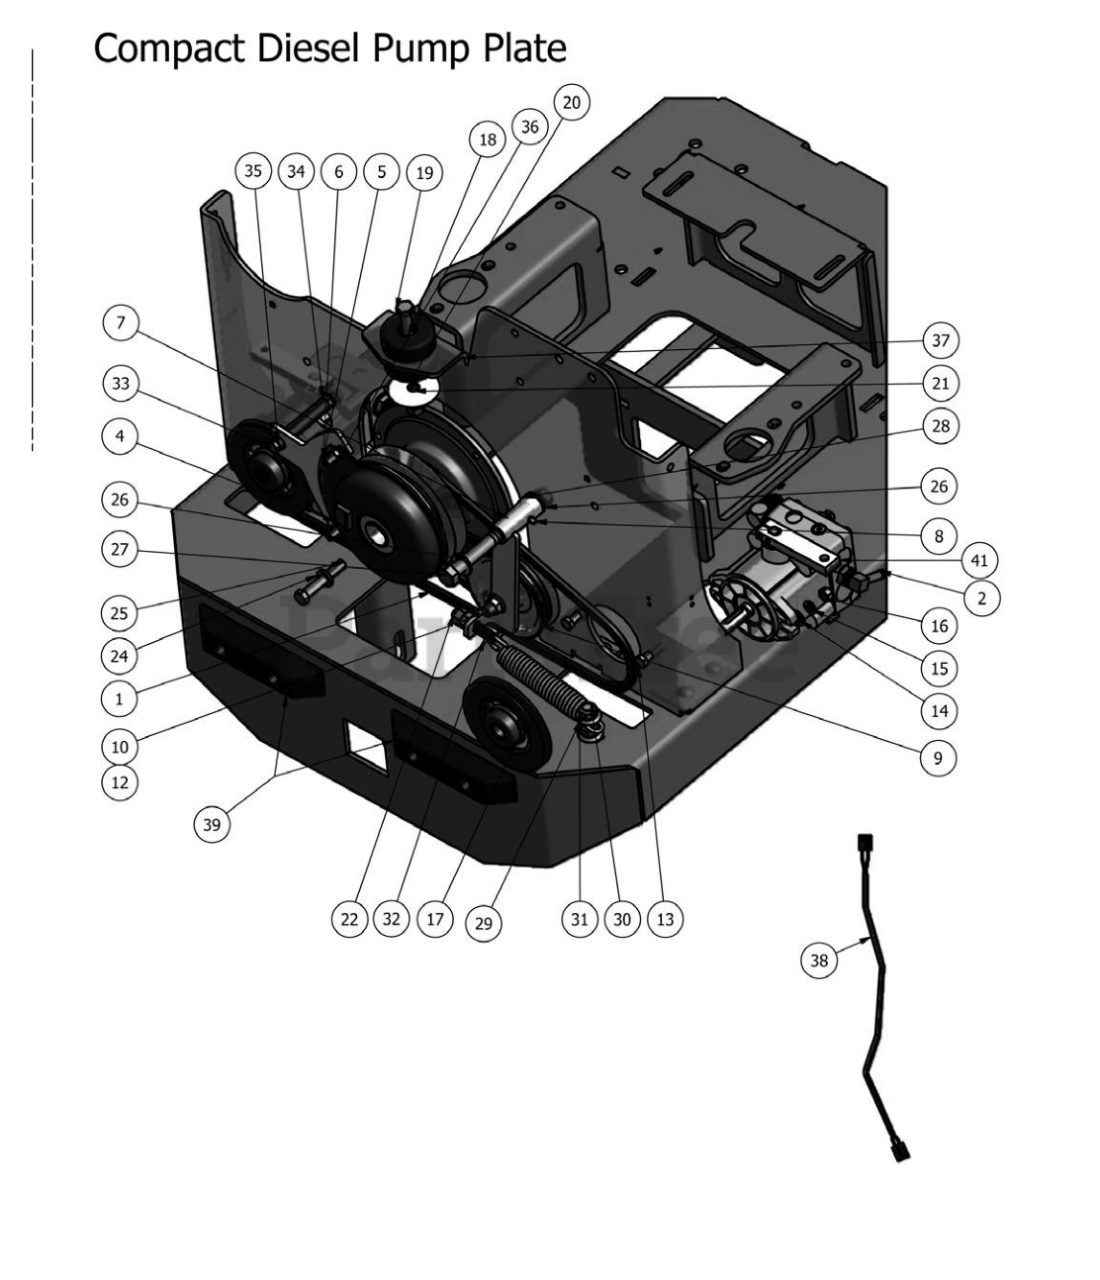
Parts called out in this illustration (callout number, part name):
2	Hydraulic Pump with Fan and Cover Left
3	Hydraulic Pump with Fan and Cover Right
4	Diesel Clutch
5	Diesel PTO Engager Holder
6	3/8" x 1 1/4" Carriage Bolt
7	Pump Idler Bracket (60 Only)
8	1/4" Drive-in Grease Fitting
9	4 3/4" Idler Pulley
10	1/2" x 2" Hex Bolt
11	5/8" x 1 1/8" Brass Bushing
12	1/2" Flange Nut
13	3/8" x 1 1/4" Hex Bolt
14	3/8" Flat Washer
15	3/8" Lock Washer
16	3/8" Hex Nut
17	5" Pump Pulley
18	Rubber Isolator
19	1/2" x 3" Bolt
20	1/2" Flat Washer
21	1/2" Lock Washer
22	1/2" Hex Nut
23	5/8" Nylock (1/2 Jam)
24	7/16" Lock Washer
25	7/16" x 2 3/4" Fine Thread Bolt
26	.635 ID Plastic Washer
27	5/8" x 4 1/2" Hex Bolt
28	1/2" Collar Spacer
29	6" Pump Idler Spring
30	1/2" x 2" Carriage Bolt
31	1/2" Nylon Flange Nut-Orange
32	1/2" x 2 1/2" All Thd Stud
33	3/8" x 4 1/2" Bolt
34	3/8" Flange Nut
35	Rubber Spacer
36	3/8" Nylock Flange Nut
37	Pump Plate Diesel
38	Clutch Pigtail
39	8" Rubber Bumper
40	5/8" Set Collar
